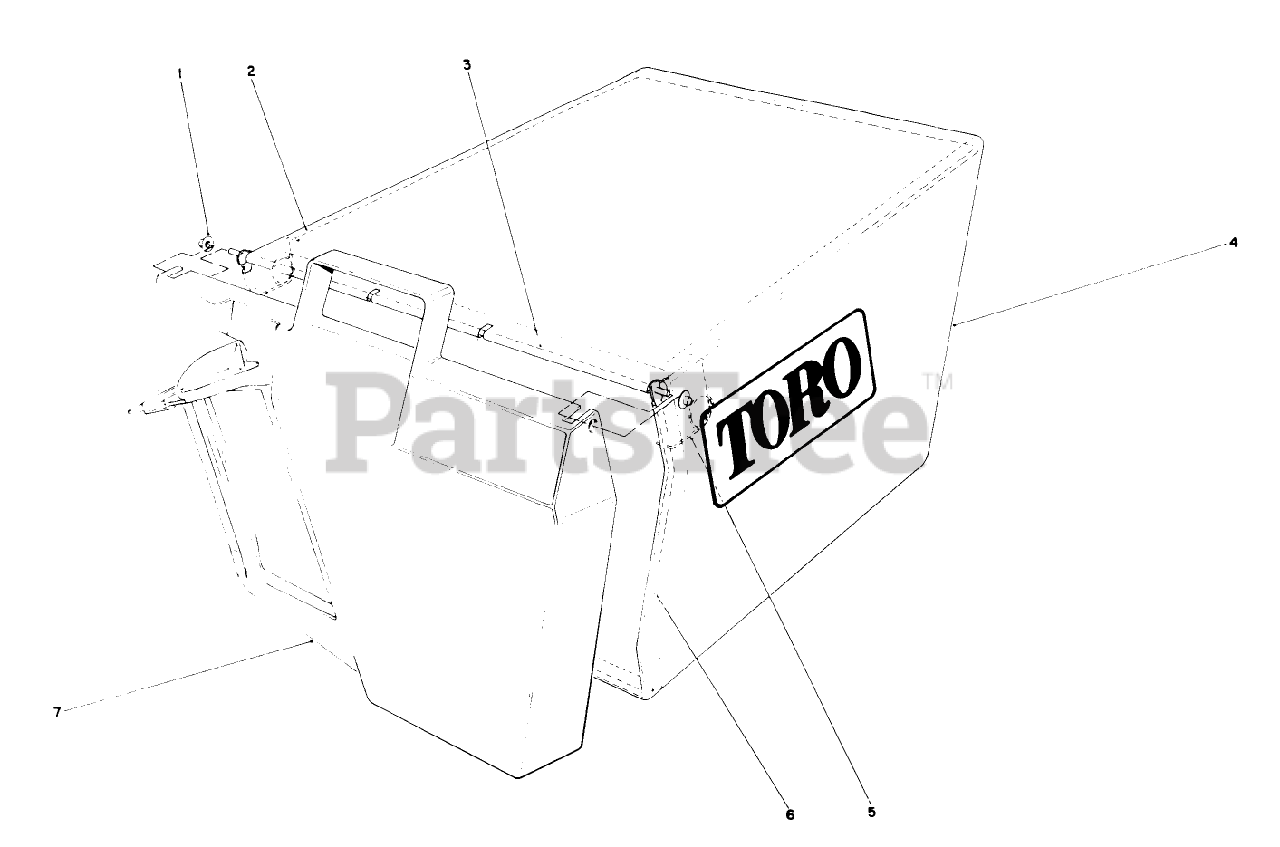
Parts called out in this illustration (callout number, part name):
1	NUT-PUSH
3	HINGE-DOOR, BAG
4	BAG-GRASS
5	SPRING
6	FRAME-BAG
7	DOOR-BAG
